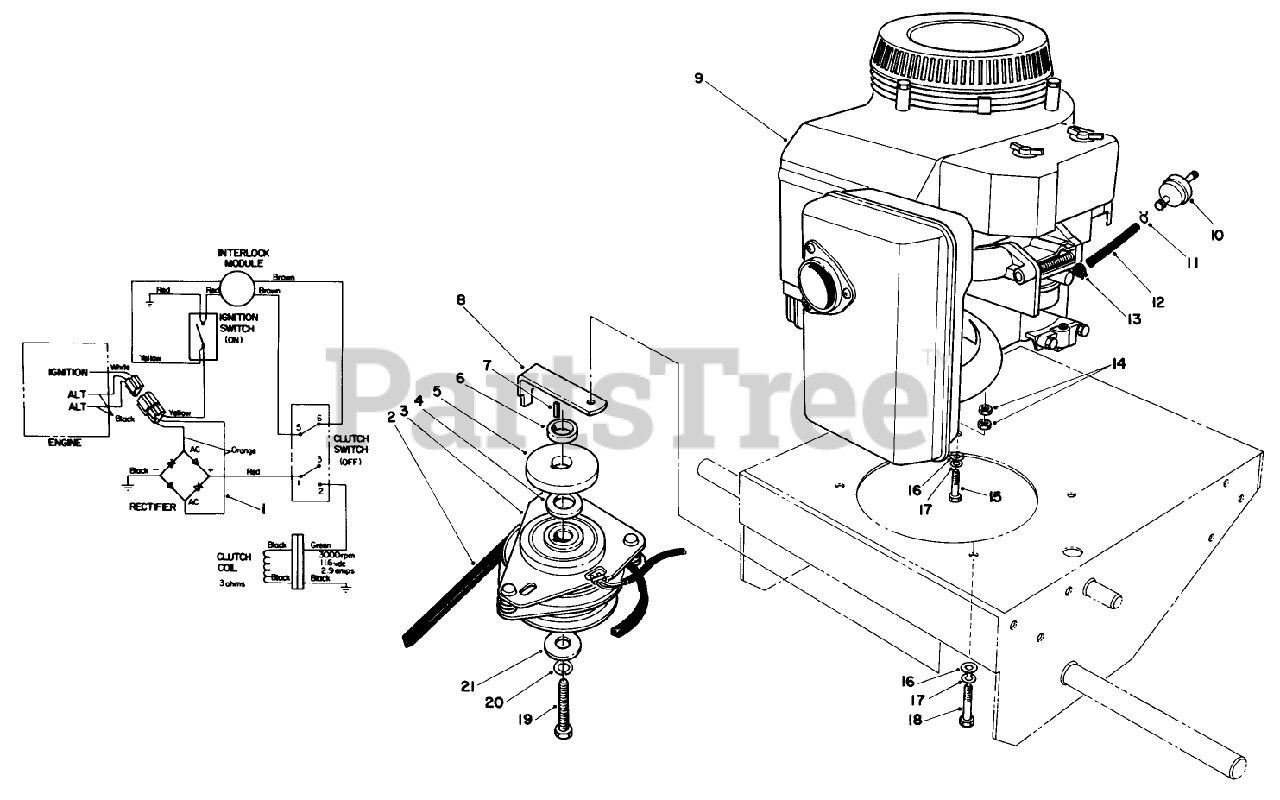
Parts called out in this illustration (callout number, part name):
2	V-BELT
7	KEY-SQUARE
9	OBTAIN LOCALLY: KAW-FB460V-BSOB-01
13	CLAMP-HOSE
14	NUT-JAM
15	SCREW
16	WASHER-PLAIN
17	WASHER-LOCK
19	SCREW-CLUTCH
20	WASHER-LOCK
